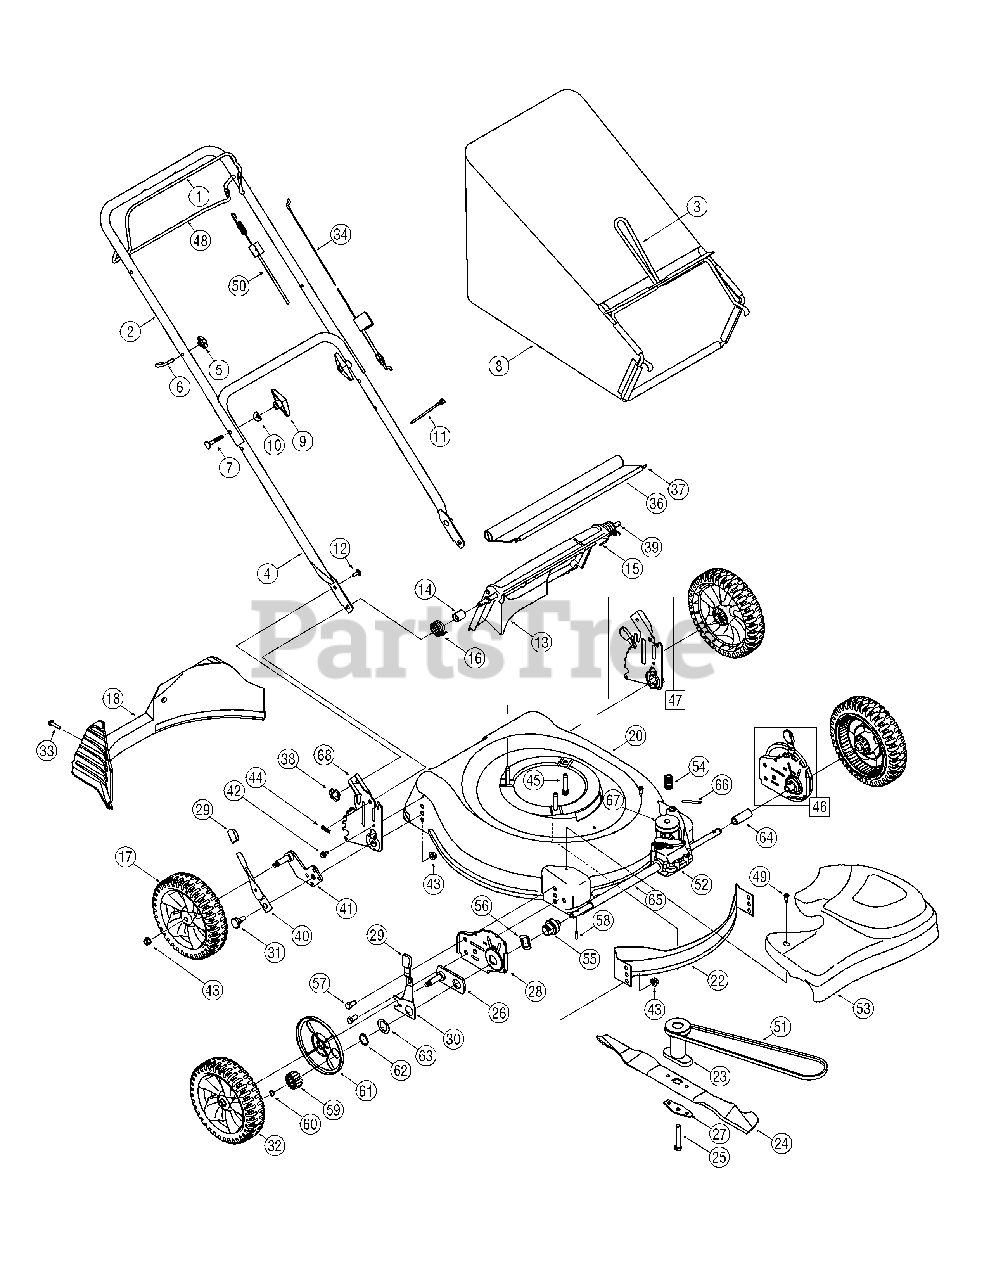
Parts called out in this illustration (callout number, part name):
5	Wing Nut
6	Rope Guide
7	Carriage Bolt ,5/16-18 x 2
8	Grass Bag Assembly
9	Hand Knob
10	Saddle Washer
11	Cable Tie
12	Carriage Bolt ,1/4-20
13	Rear Discharge Door
14	Spacer
15	Torsion Spring - LH
16	Torsion Spring - RH
17	Rear Wheel, 8" x 1.8"
18	Rear Baffle
22	Front Baffle
23	Blade Adapter w/Pulley
24	21" Standard Cut Blade
25	Hex Bolt , 3/8-24 x 2.5
26	Pivot Plate Assembly
27	Blade Bell Support
30	Front Lever - RH
30	Front Lever - LH
31	Shoulder Screw
32	Front Wheel, 8" x 1.8"
33	Screw, 1/4-15 x 1.250
34	Control Cable - 50.56"
36	Trailshield
37	Trailshield Wire
38	Wing Nut, 1/4-20
39	Rear Door Pivot Rod
40	Spring Lever
41	Pivot Arm Assembly - RH
41	Pivot Arm Assembly - LH
42	AB Screw
43	Flange Lock Nut, 3/8-16
44	Hairpin Clip
45	TT Sems Screw, 3/8-16 x 1.00
46	Ht. Adj. Assy. Front - LH
46	Ht. Adj. Assy. Front - RH
47	Rear Handle Bracket Assy. LH
47	Rear Handle Bracket Assy. RH
48	Lower Bail Handle
49	Shoulder Screw
50	Drive Cable
51	V-Belt
52	Transmission Assembly
53	Front Drive Cover
54	Belt Tension Spring
55	Bearing Assembly
56	Wave Washer
57	Hex Screw
58	Dowel Pin
59	Gear, 14T - RH
59	Gear, 14T - LH
60	Snap Ring
61	Wheel Dust Cap
62	Snap Ring
63	Washer, 1.5" OD
64	Sleeve Spacer - LH
65	Sleeve Spacer - RH
66	Roll Pin
67	Input Pulley
68	Handle Bracket use ref # 47
